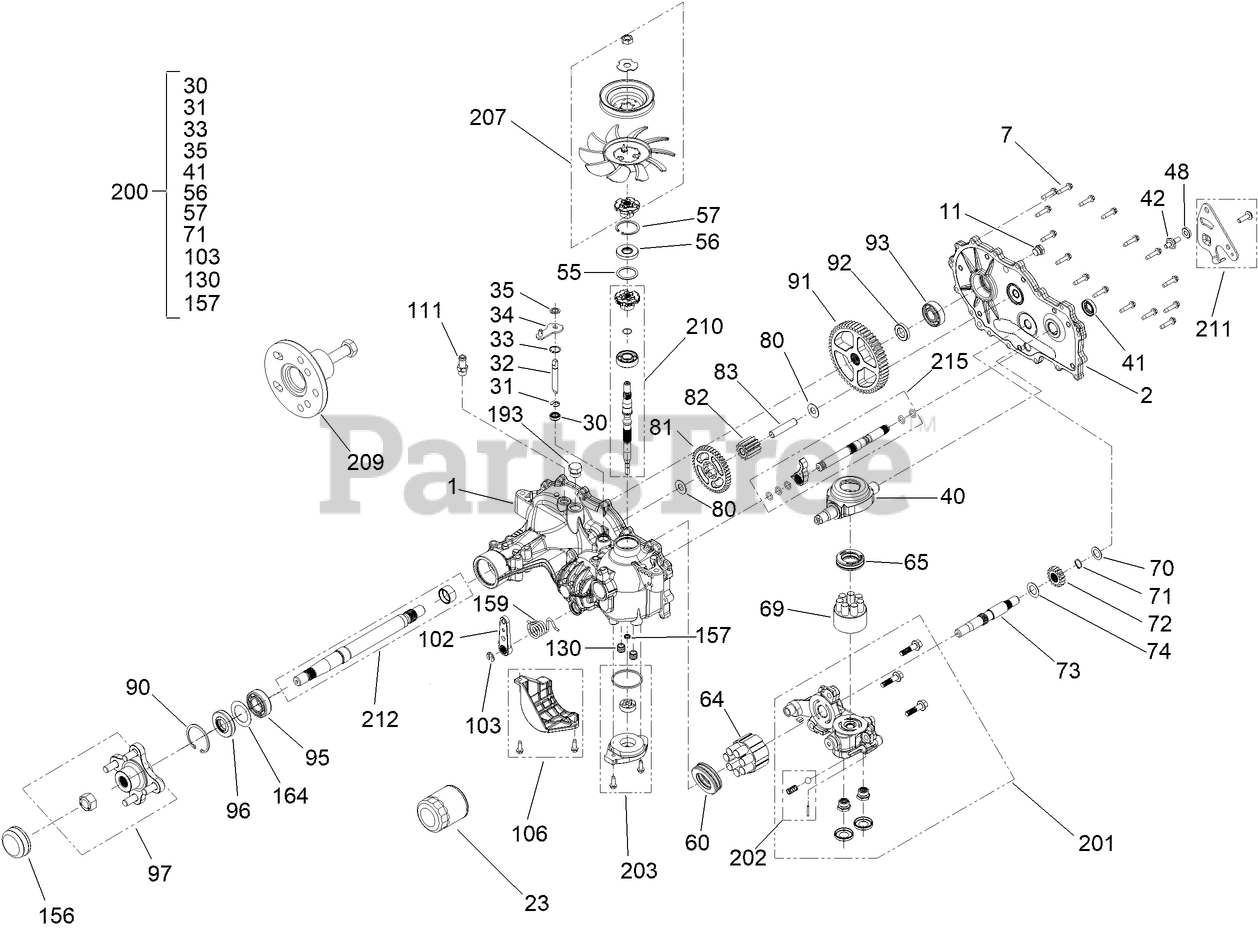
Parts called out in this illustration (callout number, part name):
1	KIT, MAIN HOUSING RH, CHARGE
2	KIT, SIDE COVER RH, CONTROL
7	SCREW-HHF
23	ELEMENT-OIL FILTER, HYD
30	SEAL-LIP
31	RING-RETAINING, EXTERNAL
32	ROD-BYPASS
33	RING-RETAINING, INTERNAL
34	ARM-BYPASS
35	RING-RETAINING, EXTERNAL
40	SWASHPLATE-TRUNNION
41	SEAL-LIP
48	SPACER
55	SPACER
56	SEAL-LIP
57	RING-RETAINING
60	BEARING-THRUST
64	CYLINDER BLOCK ASM KIT
65	BEARING-THRUST
69	PUMP BLOCK ASM
70	WASHER-FLAT
71	RING-RETAINING
72	GEAR-16T
73	SHAFT-MOTOR
74	WASHER
80	WASHER
81	GEAR-43T
82	GEAR-11T
83	PIN-JACKSHAFT
90	RING-RETAINING
91	GEAR-54T
92	SPACER
93	BEARING-BALL
95	BEARING-BALL
97	HUB KIT
102	HANDLE-BRAKE
103	RING-RETAINING, EXT
106	FILTER GUARD KIT
111	ADAPTER-STRAIGHT
130	TUBE-CHARGE
156	COVER-NUT, AXLE
157	GEROTOR SEAL KIT
159	SPRING, TORSION CCW
164	SPACER
200	SEAL KIT
201	RH CENTER SECTION KIT
202	CHARGE RELIEF KIT
203	CHARGE KIT
207	FAN AND PULLEY KIT
209	HUB PULLER KIT
210	INPUT SHAFT KIT
211	KIT, CONTROL ARM
212	AXLE SHAFT KIT
215	KIT, OUTBOARD, RH ROT A / LH ROT B
